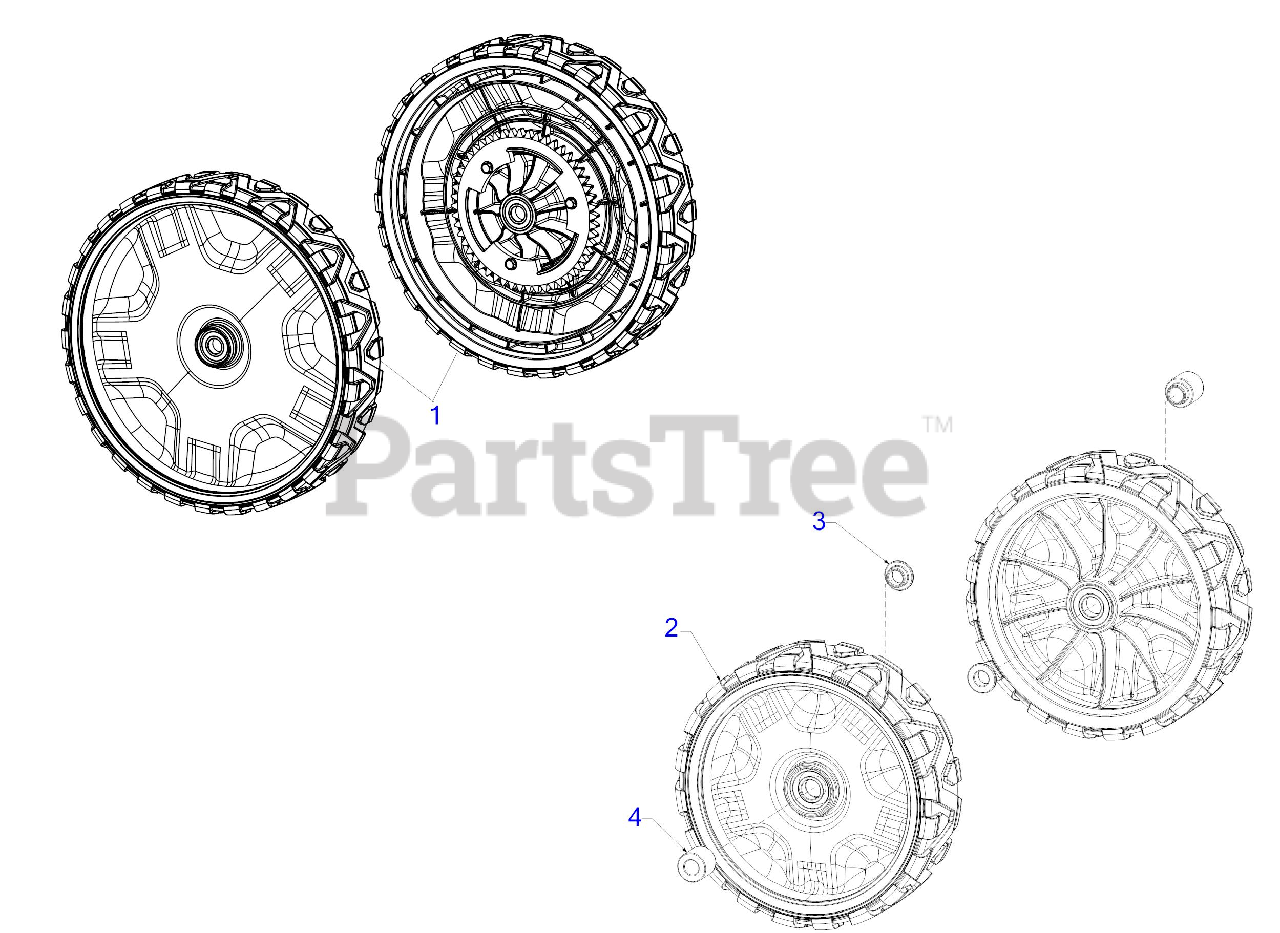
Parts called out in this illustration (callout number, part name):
1	WHEEL ASSEMBLY (11 x 2)
2	WHEEL ASSEMBLY (7 x 2)
3	CASTER HUB
4	CASTER HUB
